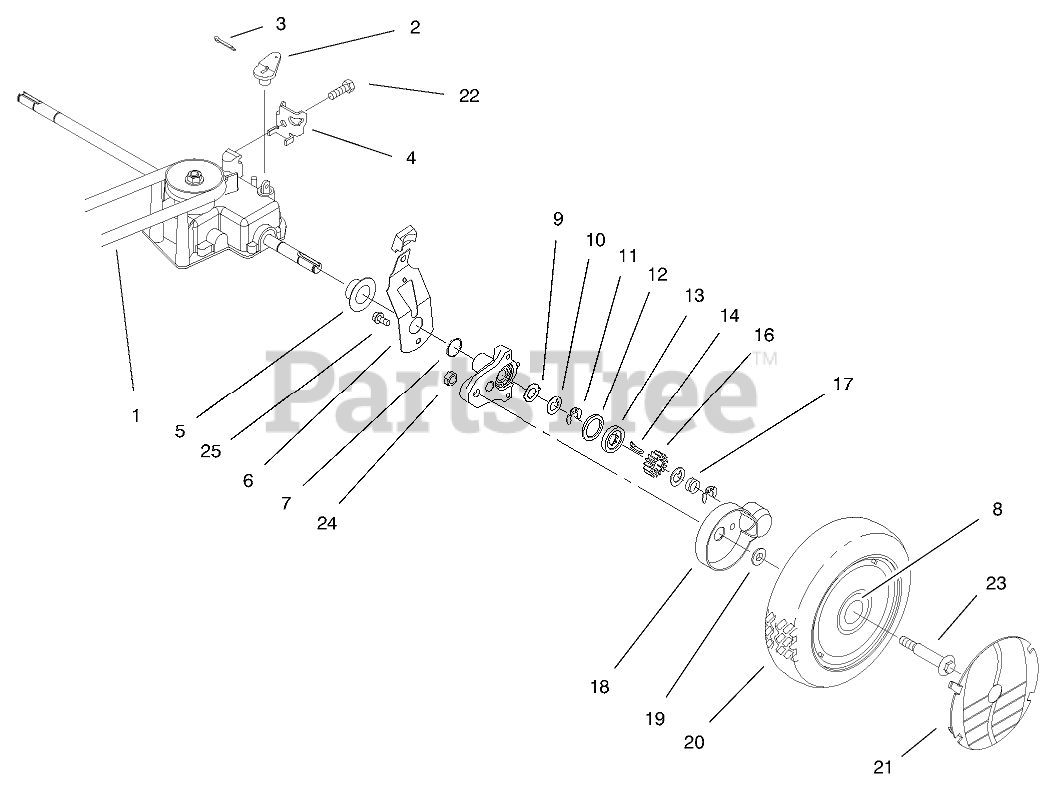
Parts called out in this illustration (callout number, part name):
1	V-BELT E
2	LEVER-SHIFT
3	PIN-COTTER
4	CLAMP-CABLE
5	CAP-END
6	SPRING ARM ASM
7	O-RING
8	BUSHING
9	WASHER-ARM, PIVOT
10	WASHER-THRUST, KEYED
11	RING-CLIP, LOCKING
12	RING-FRICTION
13	WASHER-CLUTCH
14	KEY-ROCKING, LH
16	GEAR-PINION
17	SPRING-COMPRESSION
18	COVER-WHEEL
19	SPACER-COVER, WHEEL
20	Wheel & Tire Assembly(Incl. Ref. #8)
21	WHEEL COVER
22	SCREW-HWHTF
23	BOLT-WHEEL
24	NUT-LOCK
25	SCREW-HWH
